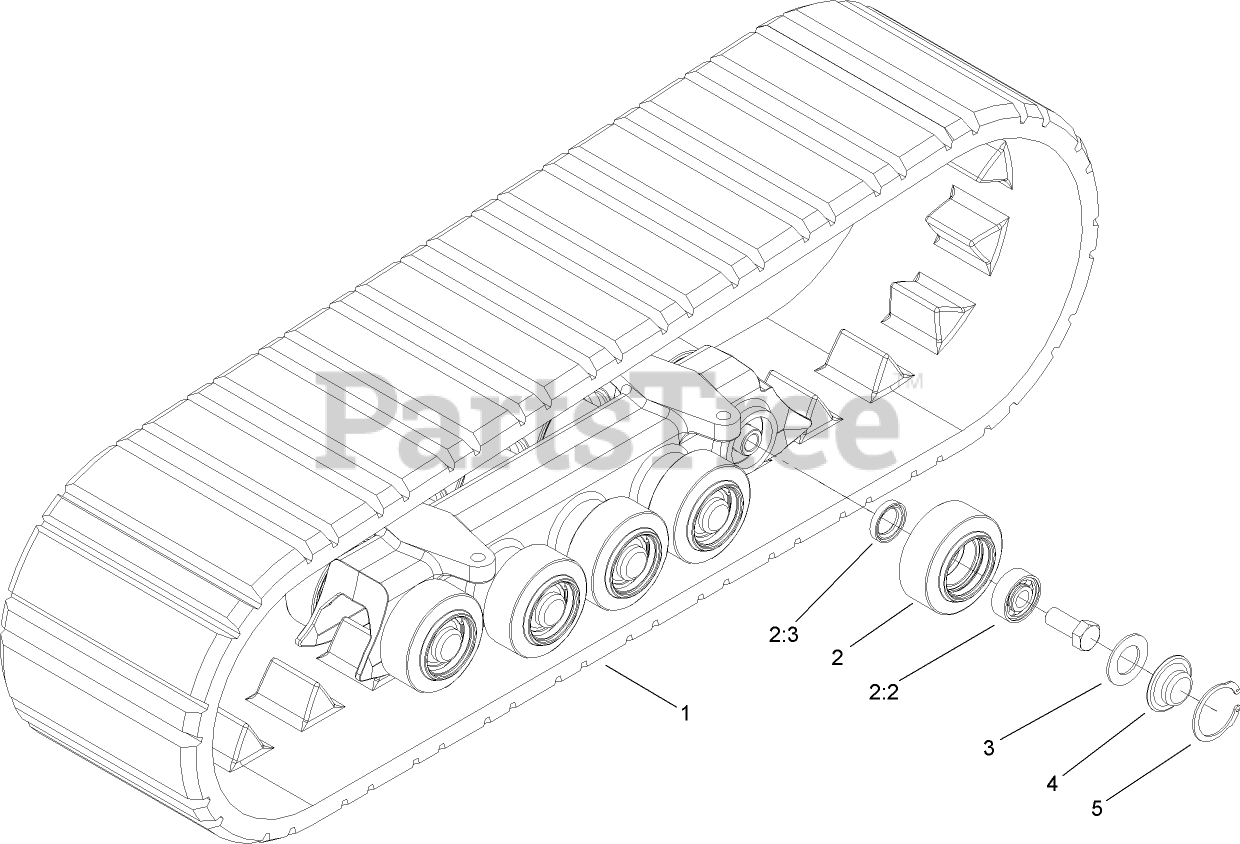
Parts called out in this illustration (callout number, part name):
2	ROAD WHEEL ASM
2:3	SEAL-OIL
3	GASKET-BOGIE
4	CAP-WHEEL, BEARING
5	RING-SNAP, INTERNAL
